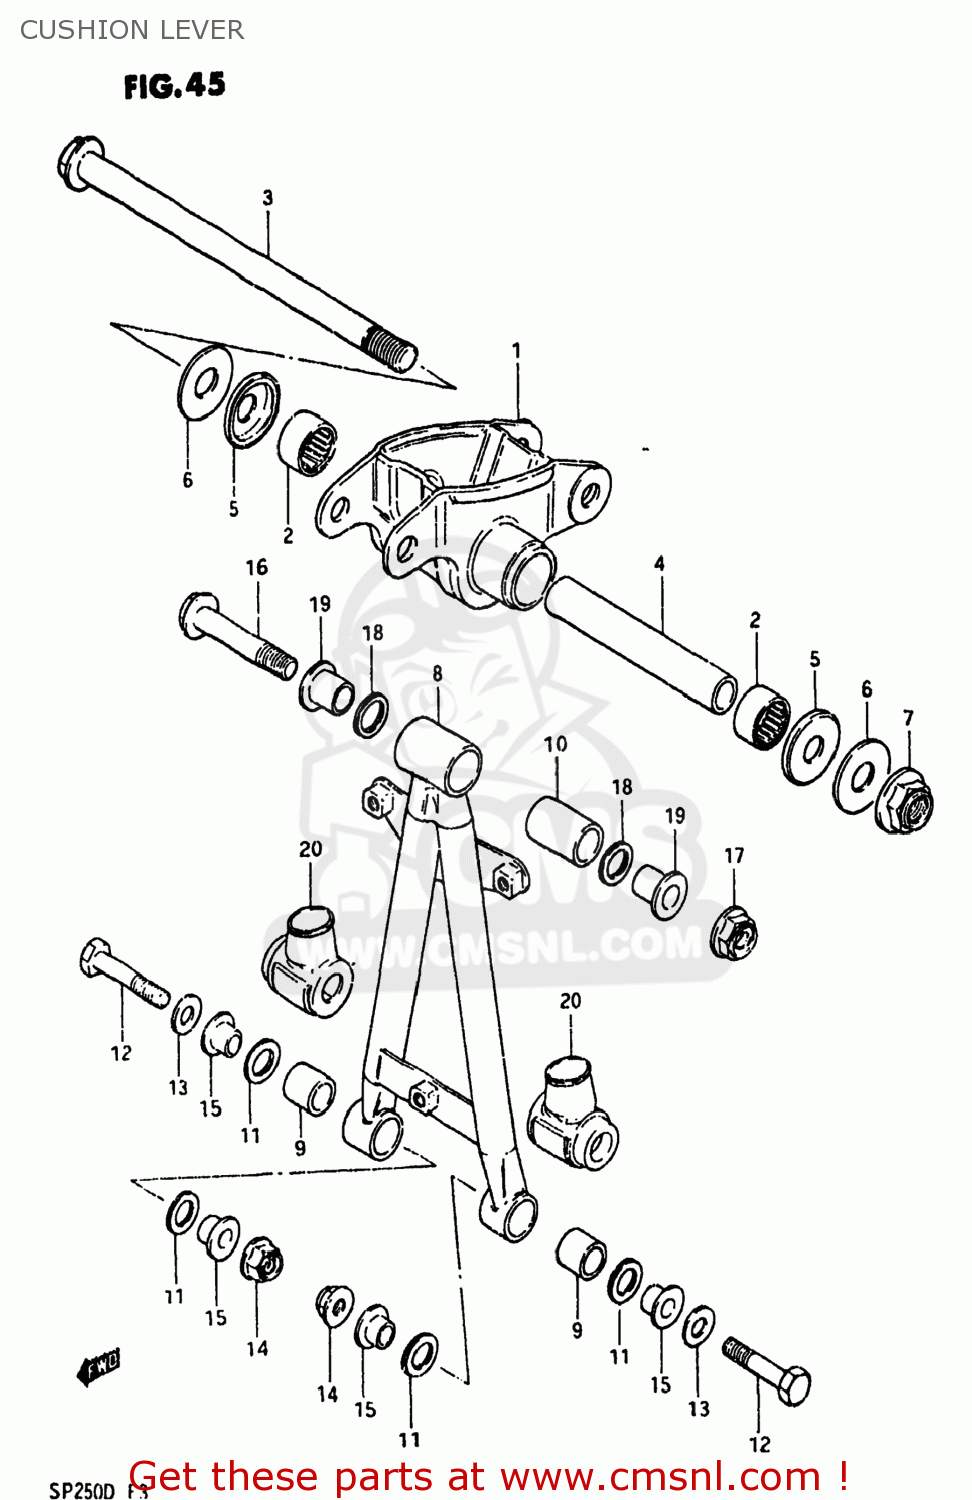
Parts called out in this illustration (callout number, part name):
1	LEVER SET,REAR CUSHION
2	BEARING(17X25X20)
3	SHAFT,REAR CUSHION LEVER
4	SPACER
5	DUST SEAL,RR CUSHION LEVER
6	WASHER
7	NUT 12MM
8	LEVER SET,REAR CUSHION
9	BUSHING
10	BUSH,UPPER
11	DUST SEAL,RR CUSHION LOD LWR
12	BOLT,REAR CUSHION ROD
13	WASHER
14	NUT
15	SPACER,RR CUSHION ROD LWR
16	BOLT(10X65)
17	NUT
18	DUST SEAL,LEVER CUSHION UNIT
19	SPACER,RR CUSHION ROD UPR
20	BOOT,REAR CUSHION ROD,LOWER
